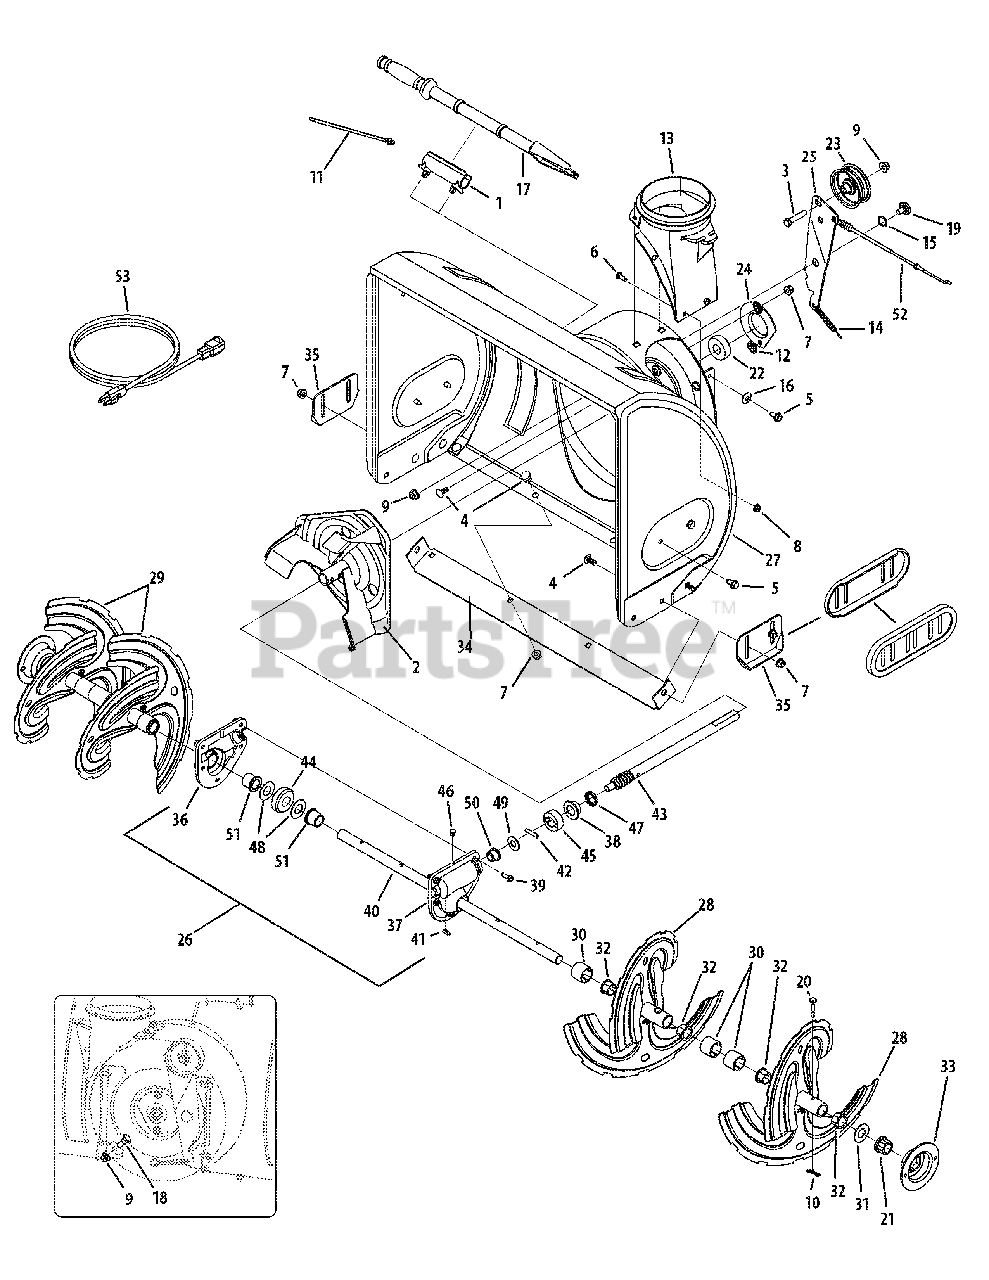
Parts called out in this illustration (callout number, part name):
1	Clean-out Tool Bracket
3	Hex Screw, 3/8-16, 1.75, Gr5
4	Carriage Bolt, 5/16-18, .750 Gr1
5	Screw, 5/16-18, 0.625
6	Carriage Screw, 1/4-20, .750, Gr5
7	Flange Lock Nut, 5/16-18, Nylon
8	Flange Lock Nut, 1/4-20, Nylon
9	Flaneg Lock Nut, 3/8-16, Nylon
10	Bow-tie Cotter Pin
11	Cable Tie, 3/16 x .05 x 7.4
13	Chute Adapter
14	Extension Spring, .38 OD x 3.6
15	Wave Washer, .625 x .885 x .015
16	Bell Washer, .340 x .872 x .060
17	Clean-out Tool
18	Shoulder Screw, .498 x .34, 3/8-16
19	Shoulder Screw, .625 x .17, 3/8-16
20	Shear Pin, .25 x 1.50
21	Hex Flange Bearing x .75 ID
22	Ball Bearing, .75 ID x 1.85 OD
23	Idler Pulley, 2.75 OD
24	Bearing Housing, 1.85 ID
26	AUger Gearbox Assembly, 22"
26	Auger Gearbox Assembly, 24"
26	Auger Gearbox Assembly, 26"
26	Auger Gearbox Assembly, 28"
26	Auger Gearbox Assembly, 30"
30	Spacer, 1.25 OD x .75 ID x 1.00
31	Flat Washer, .76 x 1.49 x .06
32	Flange Bushing, .80 ID x .91 OD
35	Skid Shoe, Standard
35	Skid Shoe. Plastic
36	Auger Housing, RH Reduced
37	Auger Housing, LH Reduced
38	Flange Bearing, .75 x 1.0 x .59
39	Sel-tapping Screw, 1/4-20, 0.750
40	Auger Axle, 22"
40	Auger Axle, 24"
40	Auger Axle, 26"
40	Auger Axle, 28"
40	AUger Axle, 30"
41	Hi-pro Key, 3/16 x 5/8
42	Dowel Pin, .25 OD x 1.2
43	Worm Shaft, .75 OD
44	Worm Gear, 20T
45	Thrust Collar
46	Plug, 1/4 x .437
47	Oil Seal, .75 x 1 x .131
48	Flat Washer, .760 ID x 1.5 OD
49	Flat Washer, .51 x 1.12
50	Flange Bearing, .75 x 1.0 x .925
51	Flaneg Bearing, .75 x 1.00 x .975
52	Auger Clutch Cable, 47.23"
53	Extension Cord, 110V, 3-Prong
